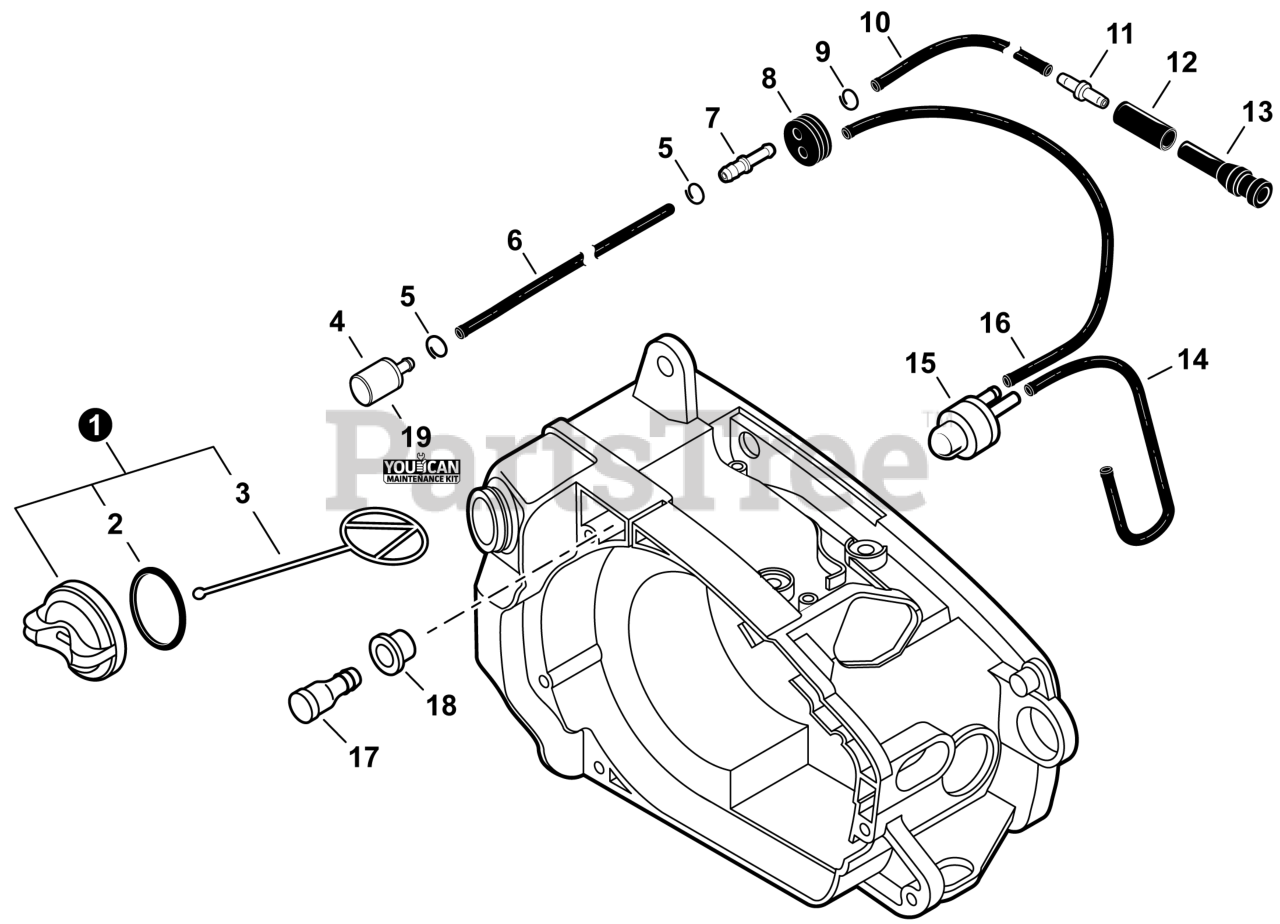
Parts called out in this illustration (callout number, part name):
1	CAP ASSY, FUEL - ORANGE
2	O-RING
3	CONNECTOR, CAP L= 60 MM
4	FILTER, FUEL
6	PIPE 3x5x75
7	CONNECTOR, PIPE 5x3.5
8	GROMMET, FUEL
10	PIPE 3x5x145
11	CONNECTOR, PIPE
12	TUBE 6.5x8.5x18
13	PIPE, FUEL 10x6x32
14	PIPE, FUEL 2.4x5x153 BLACK
15	BULB, PURGE
16	PIPE 2.4x5x258
17	VENT ASSY
18	GROMMET, FUEL
19	TUNE-UP KIT - YOUCAN™
